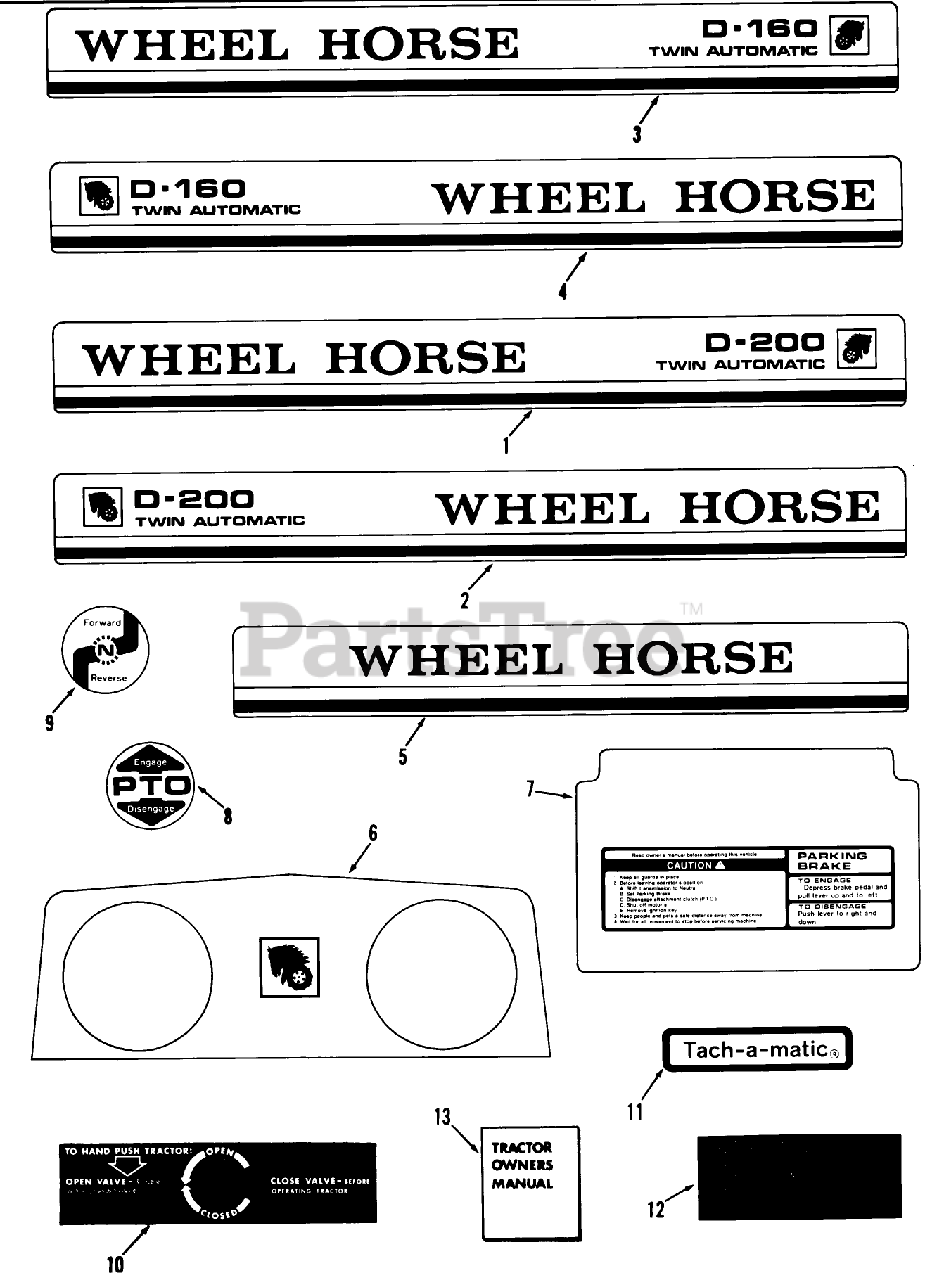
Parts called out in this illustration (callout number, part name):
7	Decal-Caution Parking Brake
8	Decal-Clutch Lever
9	Decal-Motion Control Lever
13	Owner-s Manual
